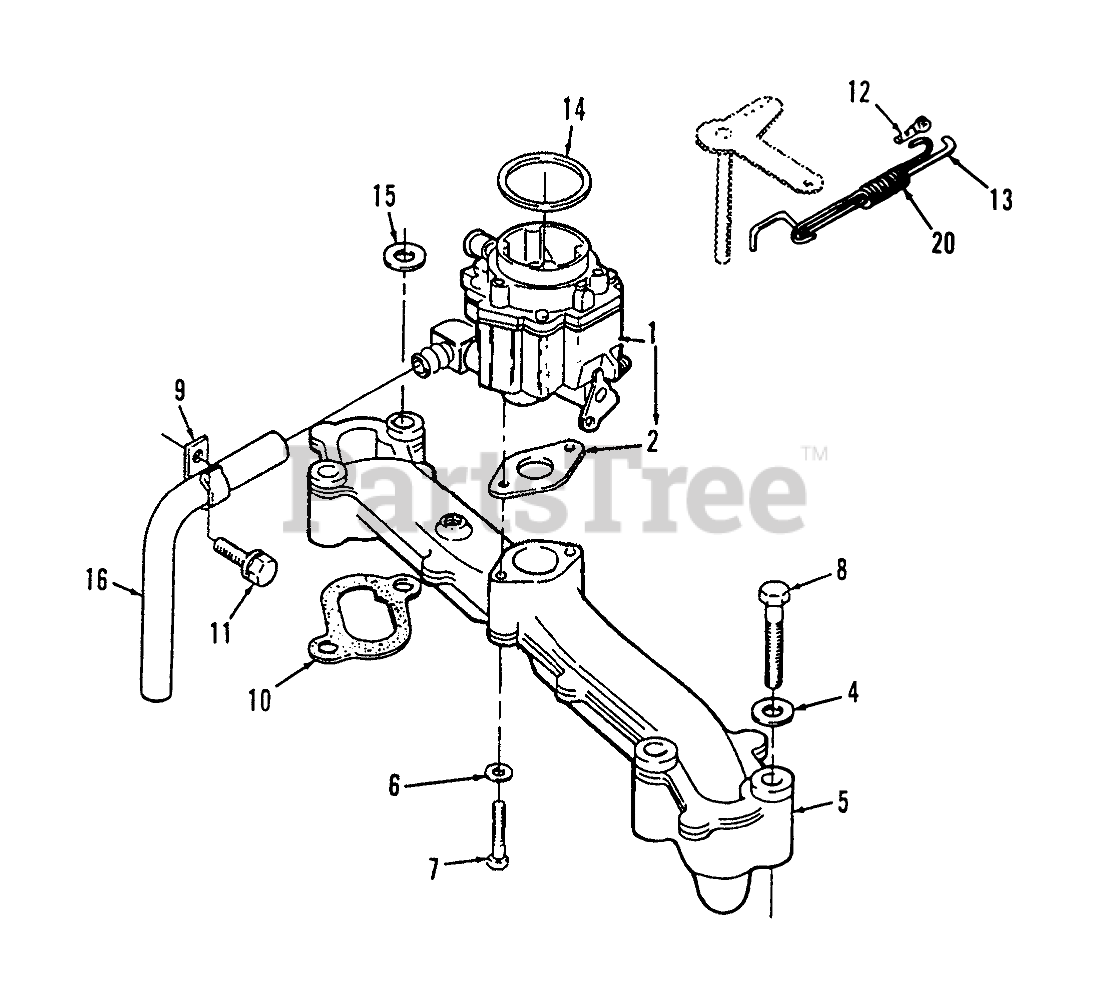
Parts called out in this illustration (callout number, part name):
1	Carburetor (Incl. Mounting Gasket, Elbow, & "O"Ring)
2	GASKET
4	WASHER-FLAT
5	MANIFOLD
6	WASHER-FLAT
7	Bolt
9	Clip
10	GASKET
11	Screw
13	GOVERNOR CONTROL ROD
15	FLAT WASHER
16	HOSE-FUEL, 24" LONG
20	Spring-Governor Rod
